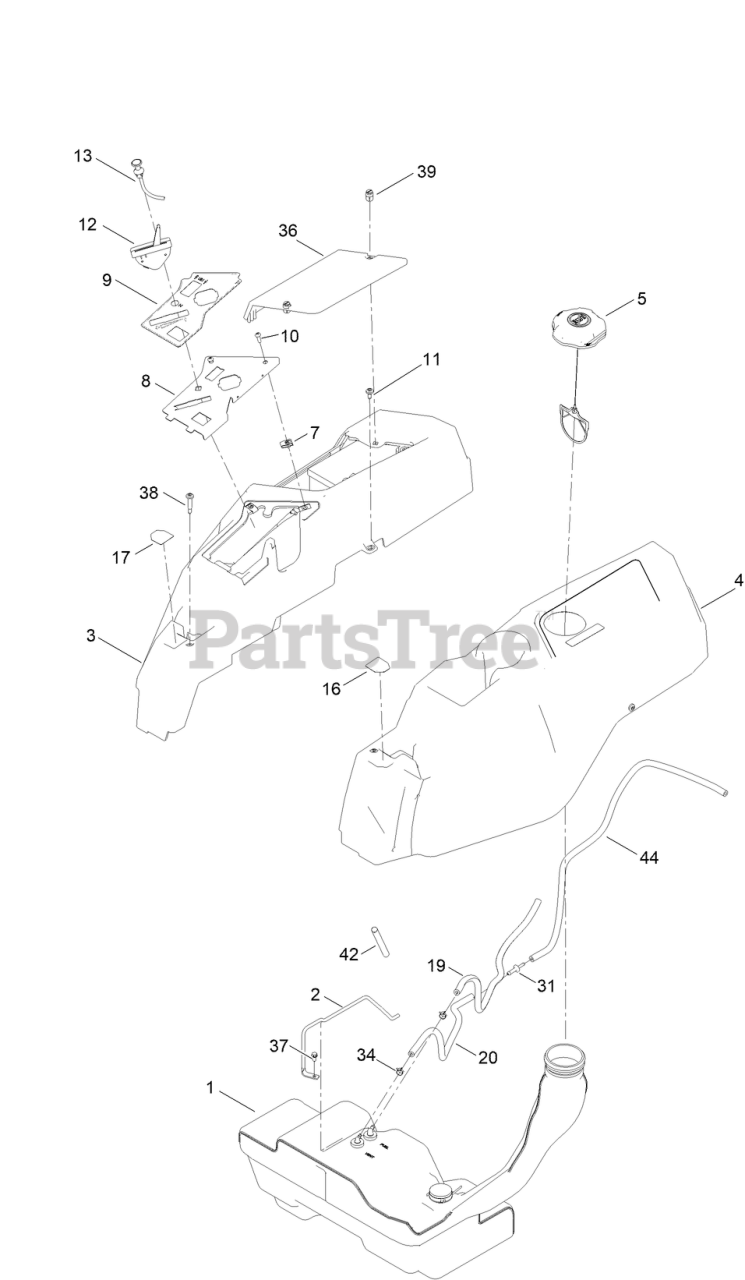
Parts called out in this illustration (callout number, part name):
1	FUEL TANK ASM
2	ROD-HOLD DOWN
3	POD-RH
4	POD-LH
5	CAP-FUEL, RATCHETING
8	PANEL-CONTROL
9	DECAL-PANEL, CONTROL
10	SCREW-PRH
11	SCREW-SHOULDER
12	CABLE-THROTTLE
13	CABLE-CHOKE
16	DECAL-LEVER, CONTROL (LH)
17	DECAL-LEVER, CONTROL (RH)
19	HOSE-FUEL
20	HOSE-FUEL
31	ADAPTOR-ORIFICE
34	CLAMP-HOSE
36	COVER-BATTERY
37	SCREW-HWH
38	SCREW-SHOULDER
39	FASTENER
42	SLEEVE-FUEL LINE PROTECTOR
44	HOSE-FUEL
